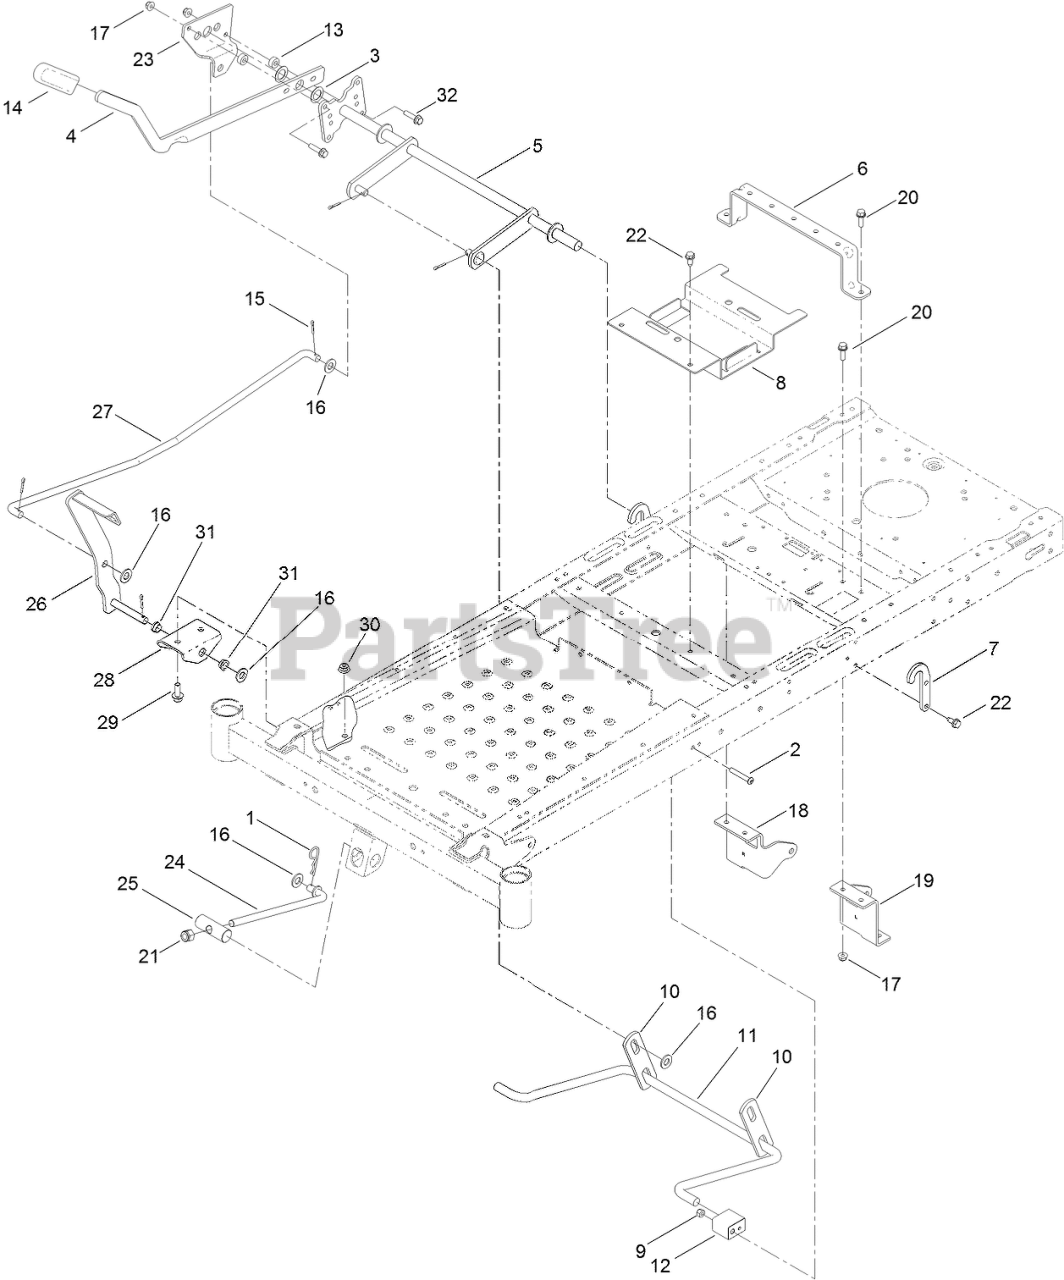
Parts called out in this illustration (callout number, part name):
1	PIN-COTTER
2	SCREW-HSBH
3	WASHER-THRUST
4	LEVER-LIFT
5	LIFT-DECK, NARROW
6	BRACE-SEAT, REAR (NARROW)
7	BRACKET-LIFT
8	BRACKET-BATTERY
9	NUT-LOCK, NI
10	LINK-LIFT
11	ARM-LIFT, REAR
12	BLOCK-PIVOT
13	SPACER
14	GRIP-LEVER
15	PIN-COTTER
16	WASHER-FLAT
17	NUT-HF, NI
18	MOUNT-HYDRO, FRONT (RH)
19	MOUNT-HYDRO, FRONT (LH)
20	SCREW-HHF
21	NUT-HEX
22	SCREW-HWHTF
23	PLATE-FOOTLIFT
24	ROD-TRUNION
25	PIN-PIVOT
27	ROD-FOOTLIFT
28	BRACKET-FOOTLIFT
29	SCREW-HHF
30	NUT-HF, NI
31	BUSHING-FLANGE
32	SCREW-HHF
